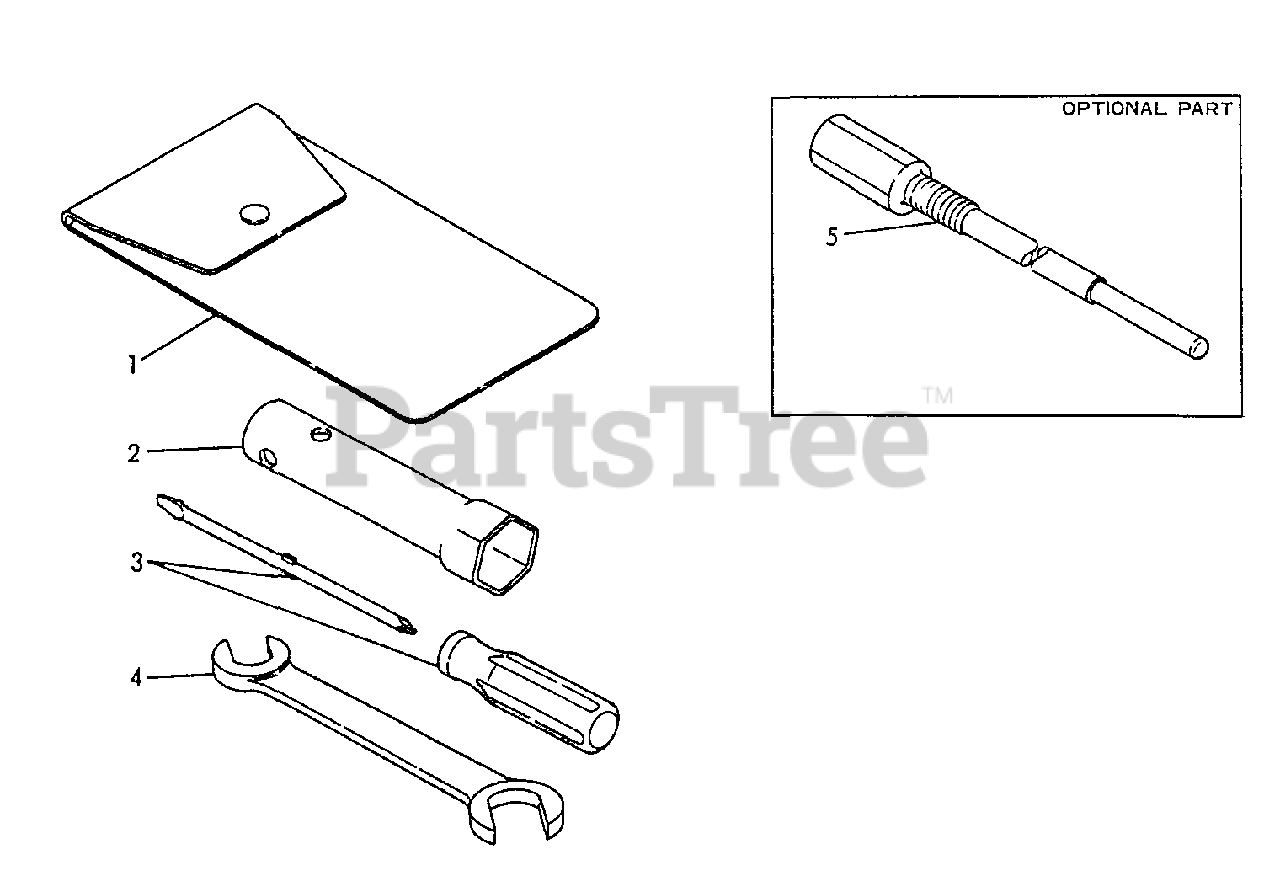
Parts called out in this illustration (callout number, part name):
1	BAG, TOOL
2	SOCKET WRENCH - 21mm
3	SCREWDRIVER
4	SPANNER - 10X12mm
5	TOOL, ROTOR REMOVAL
